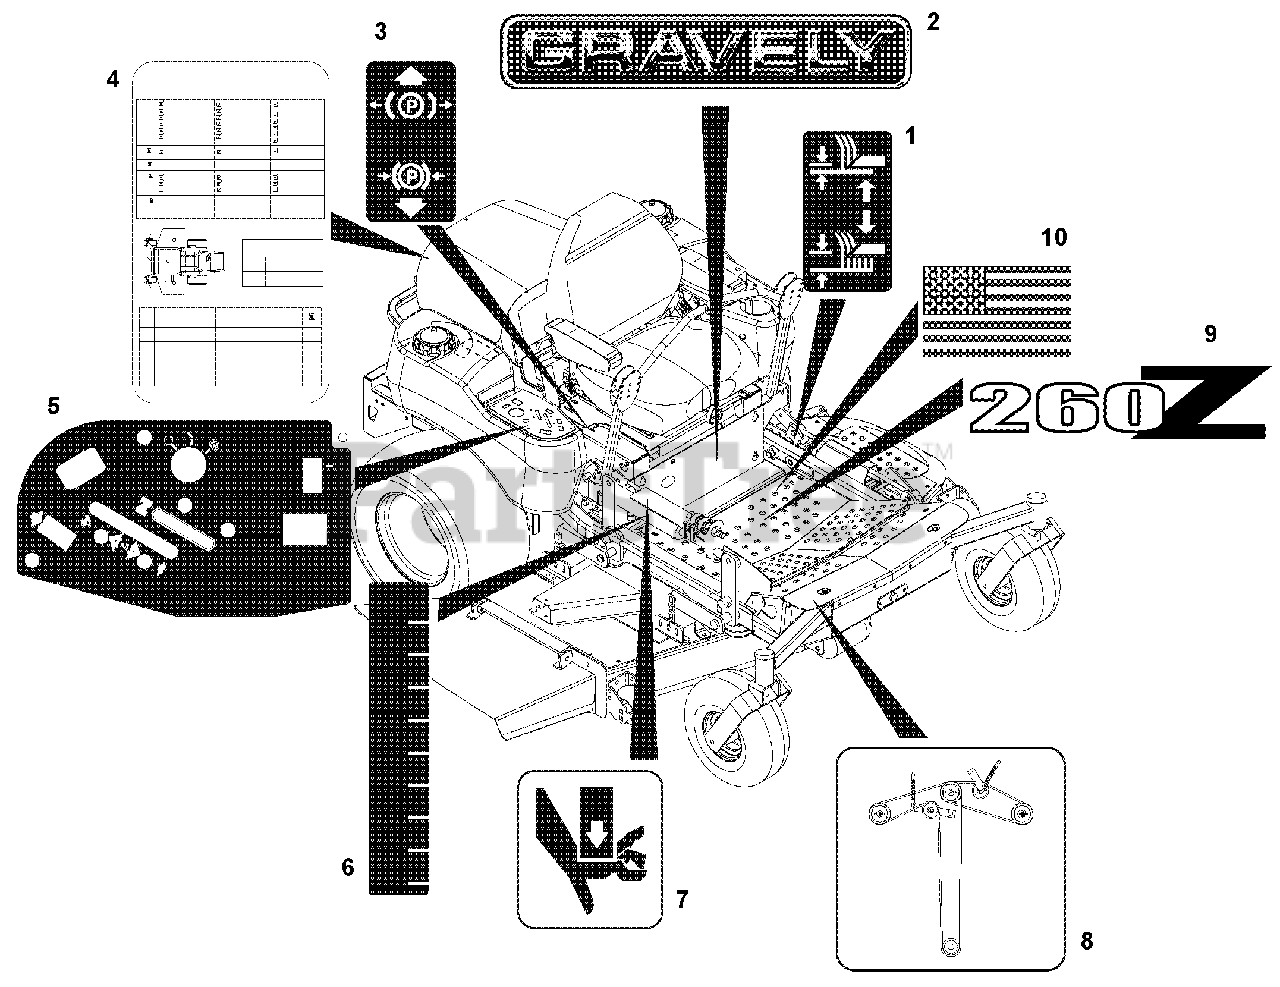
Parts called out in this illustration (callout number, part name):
1	Decal, Lift Lever
2	Decal, 15 in. Gravely Logo
3	Decal, Parking Brake Lever
4	Decal, Service Instructions
5	Decal, Control Panel (045, 046, 047, 049, 052, 053, 066, 067, 068, 070, 071, 072)
6	Decal, Height of Cut
7	Decal, Pinch Point
8	Decal, Belt Diagram (045, 046, 047, 052, 053, 066, 067, 068, 069, 071, 072)
9	Decal, PM-260Z (046, 047, 048, 053, 067, 068, 069, 072)
10	Decal, American Flag
